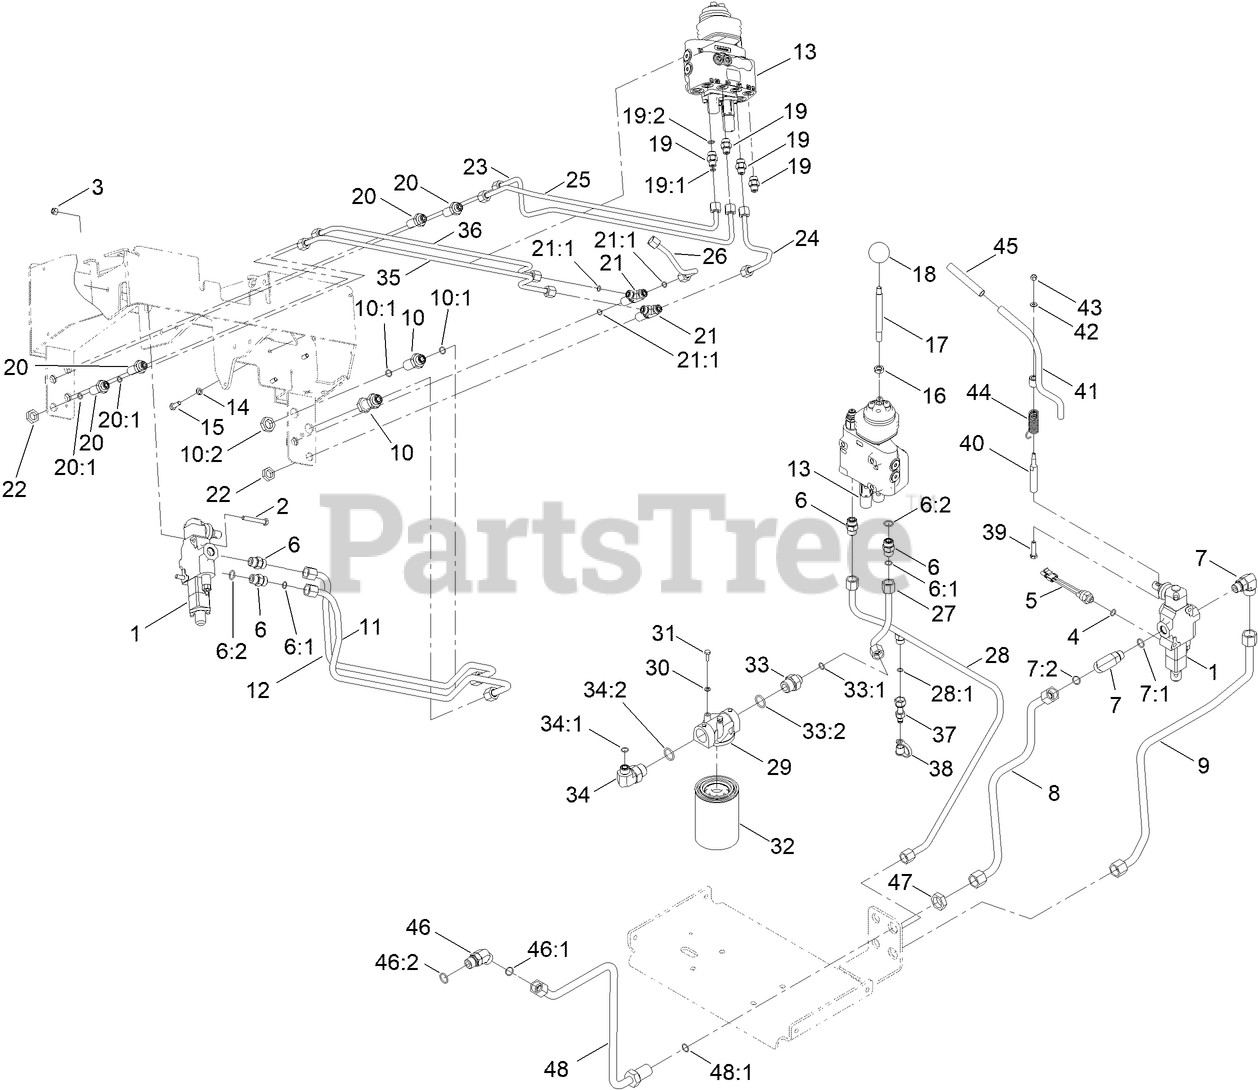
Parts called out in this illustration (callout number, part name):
1	1 SPOOL VALVE ASM
2	SCREW-HH
3	NUT-LOCK, NI
4	O-RING
5	SWITCH-BALL
6	FITTING-STRAIGHT
6:1	O-RING
6:2	O-RING
7	FITTING-ELBOW, 90 DEG
7:1	O-RING
8	TUBE-HYD
9	TUBE-HYD
10	FITTING-BULKHEAD
10:1	O-RING
10:2	NUT-BULKHEAD
11	TUBE-HYD
12	TUBE-HYD
13	2 SPOOL VALVE ASM
14	WASHER-LOCK
15	SCREW-HH
17	SHAFT-HANDLE, LOADER
19	FITTING-STRAIGHT
19:1	O-RING
19:2	O-RING
20	FITTING-STRAIGHT, BULKHEAD
20:1	O-RING
21	FITTING-TEE, BULKHEAD
21:1	O-RING
22	NUT-LOCK
23	TUBE-HYD
24	TUBE-HYD
25	TUBE-HYD
26	TUBE-HYD
27	TUBE-HYD
28	HYD TUBE ASM
28:1	O-RING
29	HEAD-FILTER
30	WASHER-LOCK
31	SCREW-HH
32	FILTER-OIL
33	FITTING-STR
33:1	O-RING
33:2	O-RING
34	FITTING-HYD, 90 DEG
34:1	O-RING
34:2	O-RING
35	TUBE-HYD
36	TUBE-HYD
37	NIPPLE-TEST
38	CAP-DUST
39	SCREW-HH
40	SPACER-HIFLO
41	LEVER-AUXILIARY
42	WASHER-FLAT
43	NUT-LOCK, NI
44	SPRING-TORSION
45	GRIP-RUBBER
46	FITTING-HYD, 45 DEG
46:1	O-RING
46:2	O-RING
47	NUT-LOCK, BULKHEAD
48	HYD TUBE ASM
48:1	O-RING
